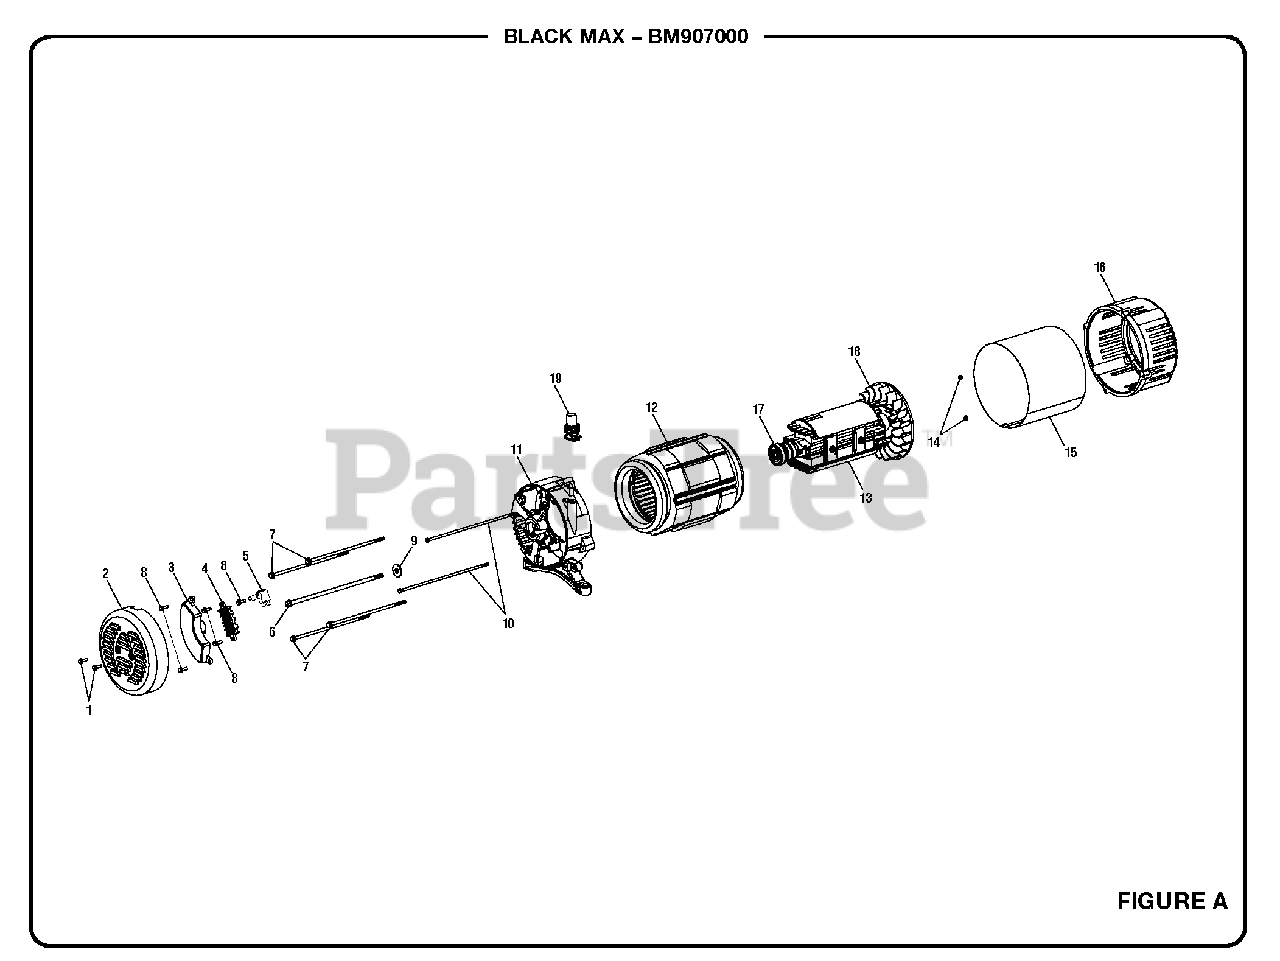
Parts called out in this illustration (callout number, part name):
1	Bolt (M5 x 12 mm, Hex Hd.)
2	Brush Cover
3	Automatic Voltage Regulator
4	Terminal Block
5	Brush Assembly
6	Rotor Bolt
7	Stator Bolt
8	Bolt (M5 x 12 mm, Hex Hd.)
9	Rotor Washer
10	Stator Bolt
11	Bearing Housing
12	Stator Assembly
13	Rotor Assembly
14	Hex Nut (M5)
16	Engine Adaptor
19	Rubber Boot
